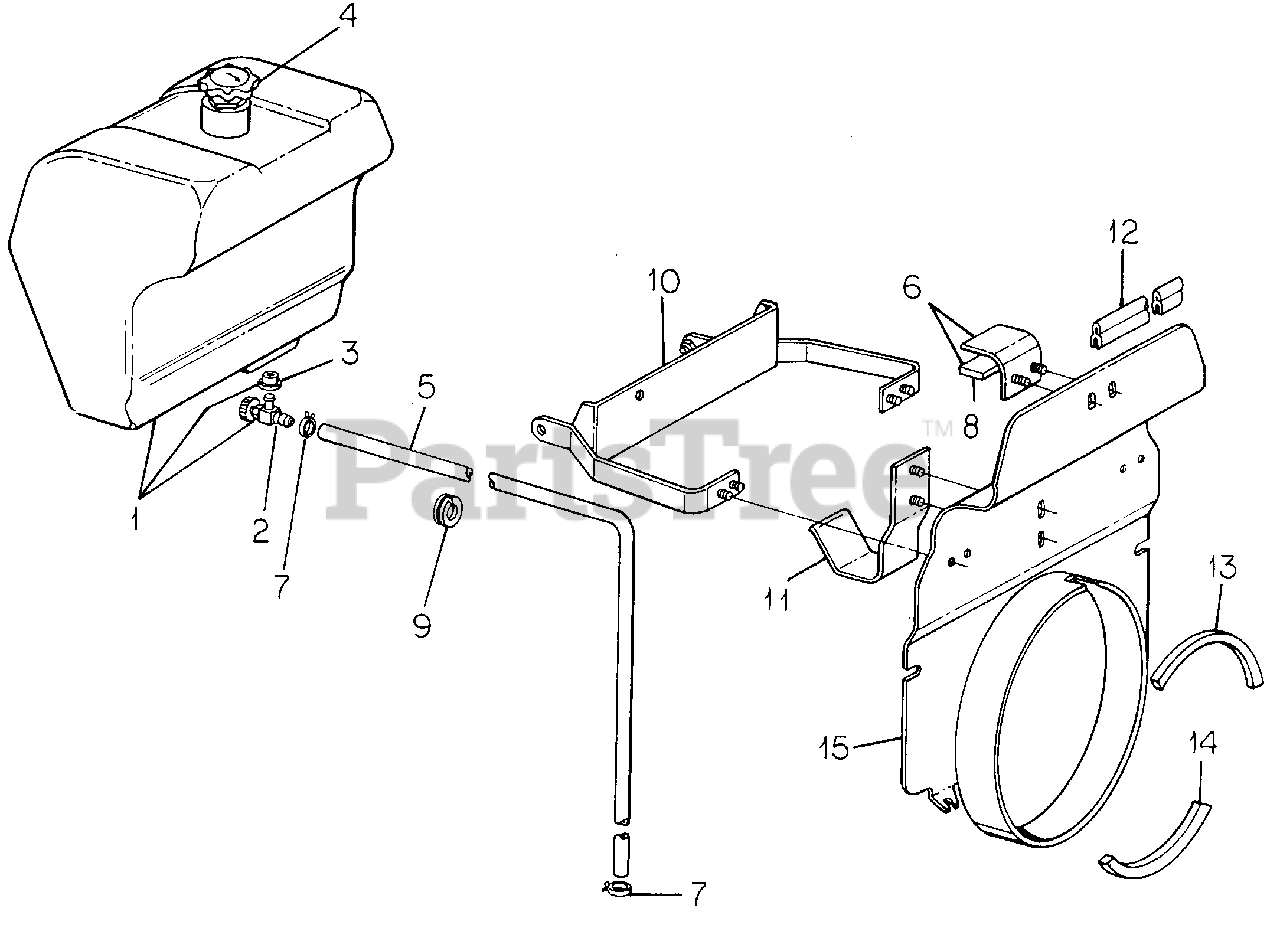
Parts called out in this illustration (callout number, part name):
1	Tank Assy, Fuel
2	Valve, Shut-Off
3	Bushing
4	Cap w/Gauge
5	Line, Fuel
6	Clamp Assy, Fuel Tank
7	Clamp, Hose
8	Strip, Fuel Tank Pad
10	Support Assy, Fuel Tank
11	Support Assy, Fuel Tank Bottom
12	Seal, Heat Baffle
13	Not used in this application
14	Not used in this application
15	Deflector, Heat
